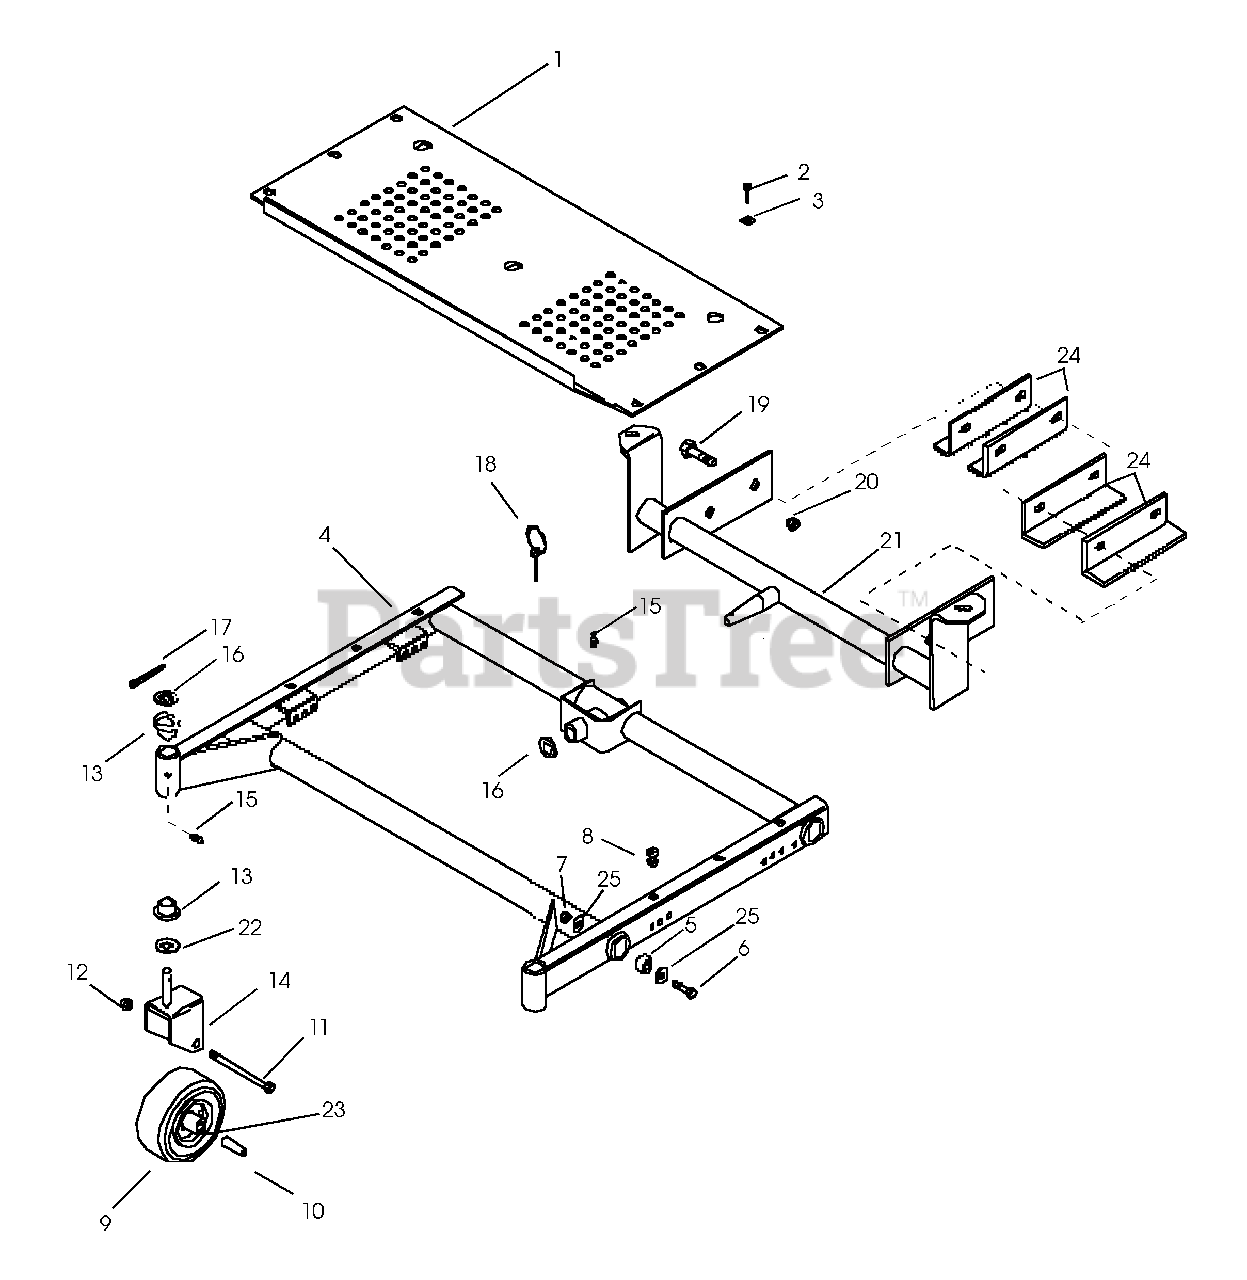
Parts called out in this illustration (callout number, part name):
1	Footboard
2	Screw-Machine-Hex Washer Head .25-20 x .75
3	Washer-Flat-Steel .281 x .620 x .065
4	Frame-Mower
5	Bushing .391 x .626 x .670
6	Bolt-Hex .38-16 x 1.50 Grade 5
7	Nut-Locking-Center .38-16
8	Clip-U-Type
9	Wheel-Gauge 11 x 4-4
10	Bushing-Caster Fork
11	Bolt-Hex .50-13 x 6.50 Grade 5
12	Nut-Locking-Center .50-13
13	Bushing-Flange 1.020 x 1.385 x .75 x 1.75
14	Weldment-Castor Fork
15	Fitting-Lube .25-28 x .256
16	Washer-Hardened-Thrust 1.002 x 1.552 x .030
17	Pin-Cotter .18 x 1.50
18	Pin-Klik .25 x 1.75
19	Bolt-Hex .62-11 x 1.50
20	Nut-Locking-Center .62-11
21	Weldment-Mower Frame Mounting
22	Washer-Flat-Steel 1.007 x 1.542 x .062
23	Bearing-Ball-Flange .752 x 1.50 x .50
24	Plate/Shim
25	Washer-Flat-Steel .406 x .812 x .065
